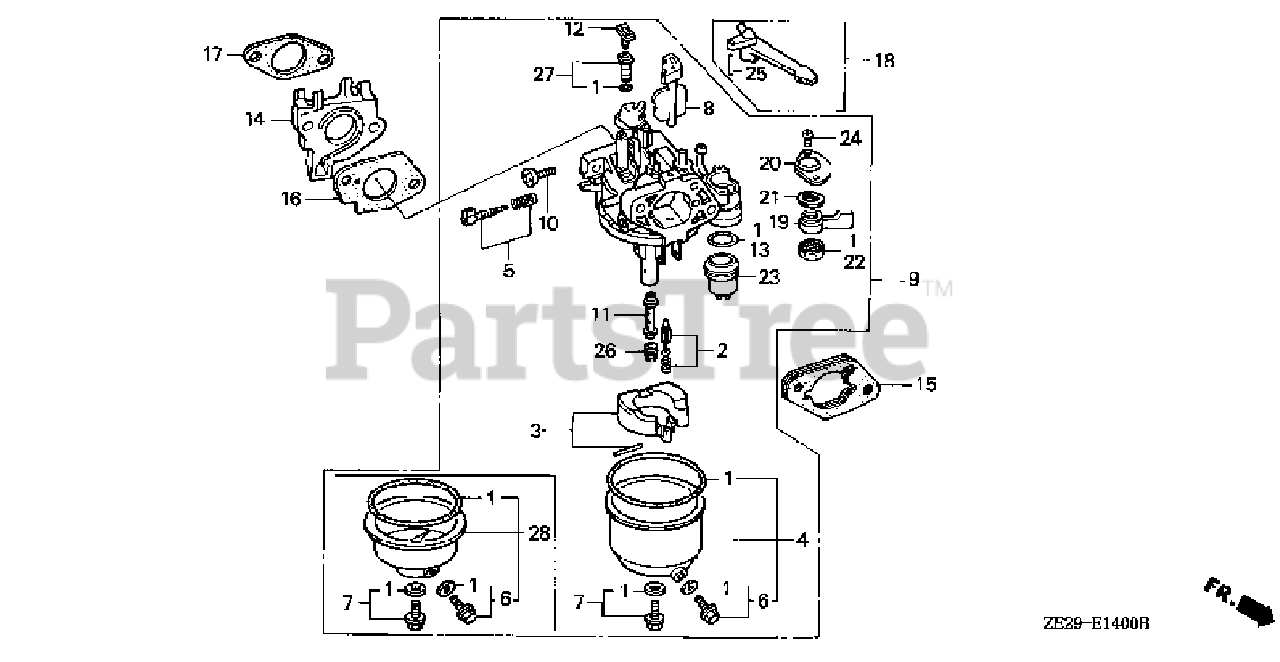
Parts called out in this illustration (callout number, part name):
1	GASKET SET
2	VALVE SET, FLOAT
3	FLOAT SET
4	CHAMBER SET, FLOAT
5	SCREW SET
6	SCREW SET, DRAIN
7	SCREW SET B
8	CHOKE SET
9	CARBURETOR ASSY. (BE70B B)
10	SCREW, THROTTLE STOP
11	NOZZLE, MAIN
12	COLLAR, SET
13	GASKET, FUEL STRAINER CUP
14	INSULATOR, CARBURETOR
15	SPACER, CARBURETOR
16	GASKET, CARBURETOR
17	GASKET, INSULATOR
18	LEVER, CHOKE (STD)
19	LEVER, VALVE
20	PLATE, LEVER SETTING
21	SPRING, VALVE LEVER
22	GASKET, VALVE
23	CUP, FUEL STRAINER
24	SCREW, PAN (3X6)
24	SCREW, PAN (3X8)
25	PIN, SPRING (2X12)
26	JET, MAIN (#82)
26	JET, MAIN (#85)
26	JET, MAIN (#88)
27	JET SET, PILOT (#40)
28	CHAMBER SET, FLOAT
